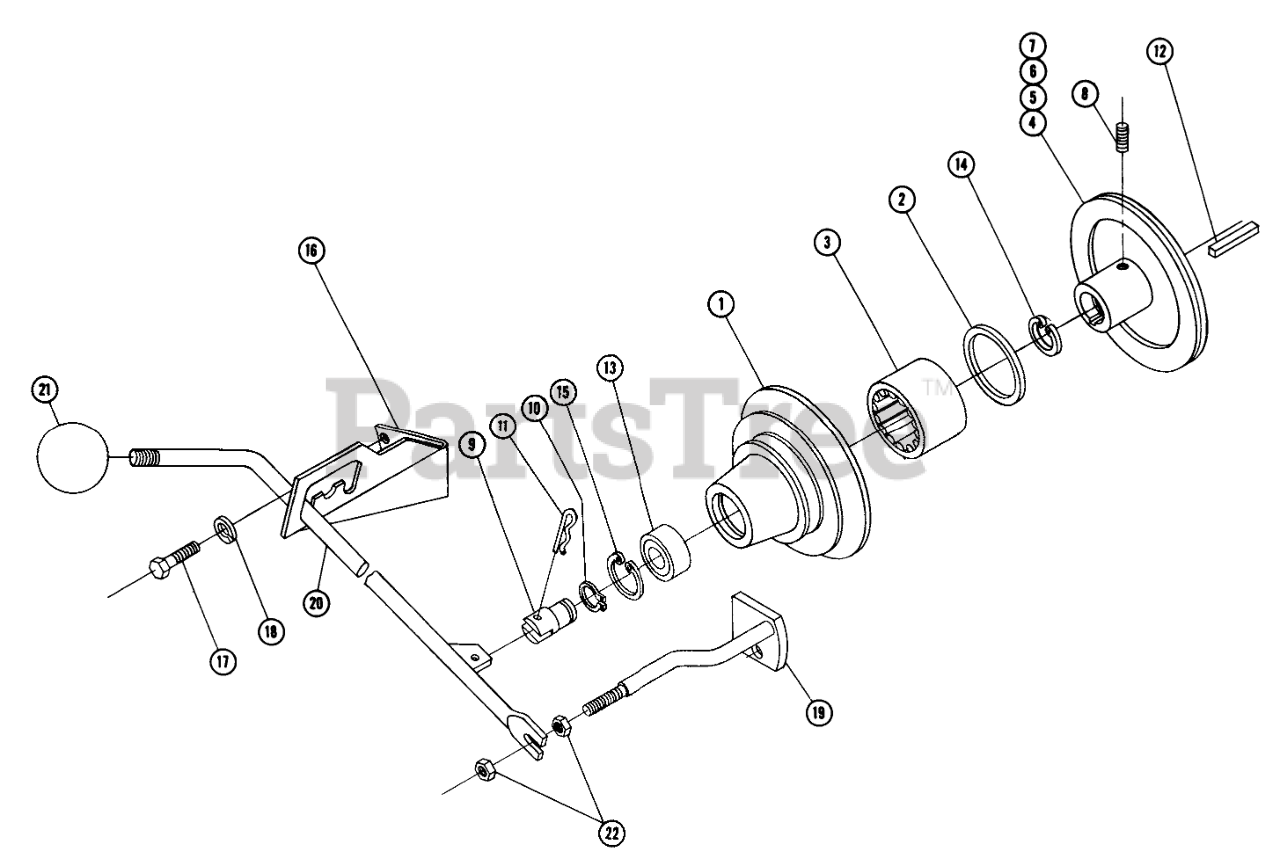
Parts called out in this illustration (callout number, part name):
1	Housing
2	OIL SEAL
3	Bearing-Needle
4	Ass-y.-Clutch Plate (Complete)
5	Assembly-Clutch Plate-Sleeve
6	CLUTCH FACING
7	Rivet-Clutch Facing
8	Set Screw 1/4-20 x 1/4
9	SHAFT
10	Snap Ring 3/4 I.D.
11	Hairpin
12	KEY-SQUARE
13	Bearing
14	Snap Ring-1 1/8 Int. Truarc
15	Snap Ring-1 3/4 Int. Truarc
16	Bracket
17	Bolt Hex 5/16-18
18	Lockwasher
19	Ass-y.-Plate
20	ROD ASSY
21	Knob
22	3/8-16 E.S.
23	DECAL
24	Wrench 1/8 Hex Allen
